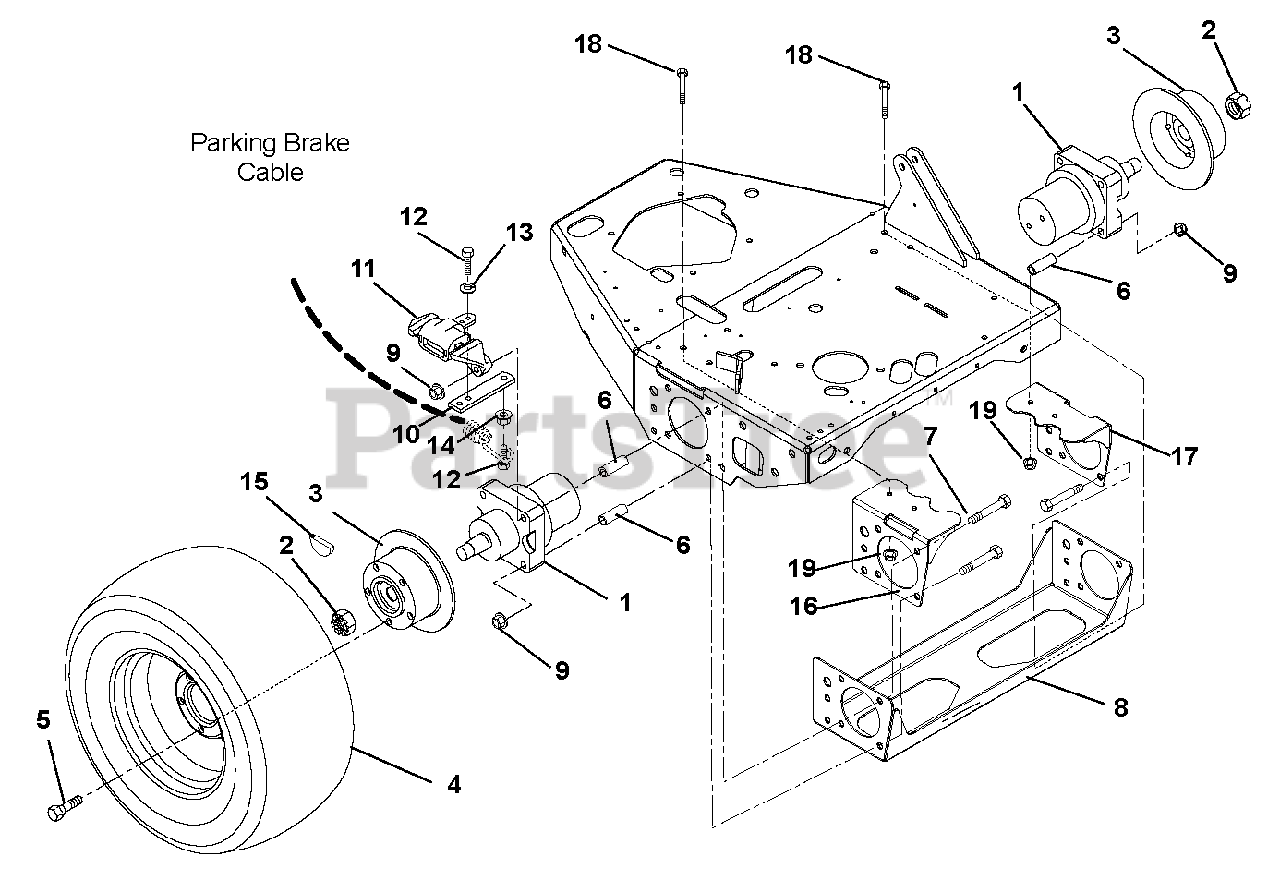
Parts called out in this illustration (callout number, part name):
4	2
9	8
12	6
13	4
14	2
18	4
19	4
